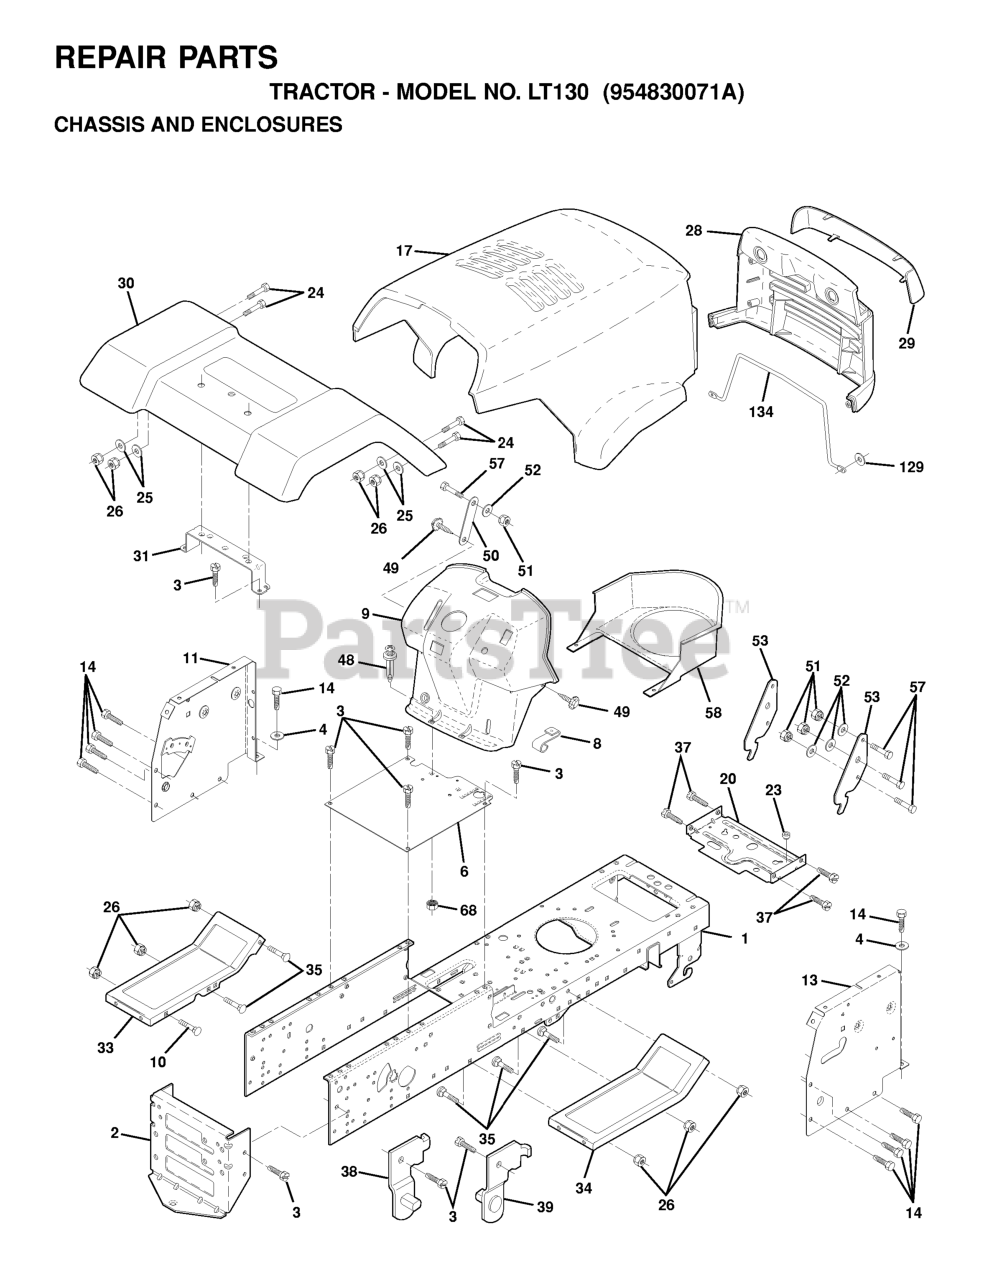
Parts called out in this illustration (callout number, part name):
1	CHASSIS WELD 11GA.95
2	STRETCH DRAWBAR
3	SCREW
4	Washer 13/32 X 3/4 X 16 Ga.
6	SADDLE LT FENDER
8	CLIP,INSULATOR
10	BOLT D
13	PANEL.DASH.RH
17	HOOD LT/PL HUSQVARNA
20	PLATE MTG BATTERY FUEL TAND
23	BUSHING.SNAP.NYL.BLK.
25	WASHER
26	NUT
28	GRILLE LT/PL HUSQVARNA
29	LENS LT/PL HUSQVARNA
30	FENDER
31	BRACKET FENDER
33	FOOT REST LH
34	FOOTREST RH
37	Screw 5/16-18 x 1/2 Hex, Self Tapping 5/16-18 x 1/2
38	BRACKET LH PIVOT
39	BRACKET RH PIVOT
48	RIVET PUSH
49	SCREW HEX CRT
51	LOCKNUT.NYLOC.1/4-20
53	BRACKET PNT PICK OFF LT/PL
57	BOLT
58	AIR DUCT
68	NUT
134	ROD SUPPORT HOOD LT/PL HUSQ
